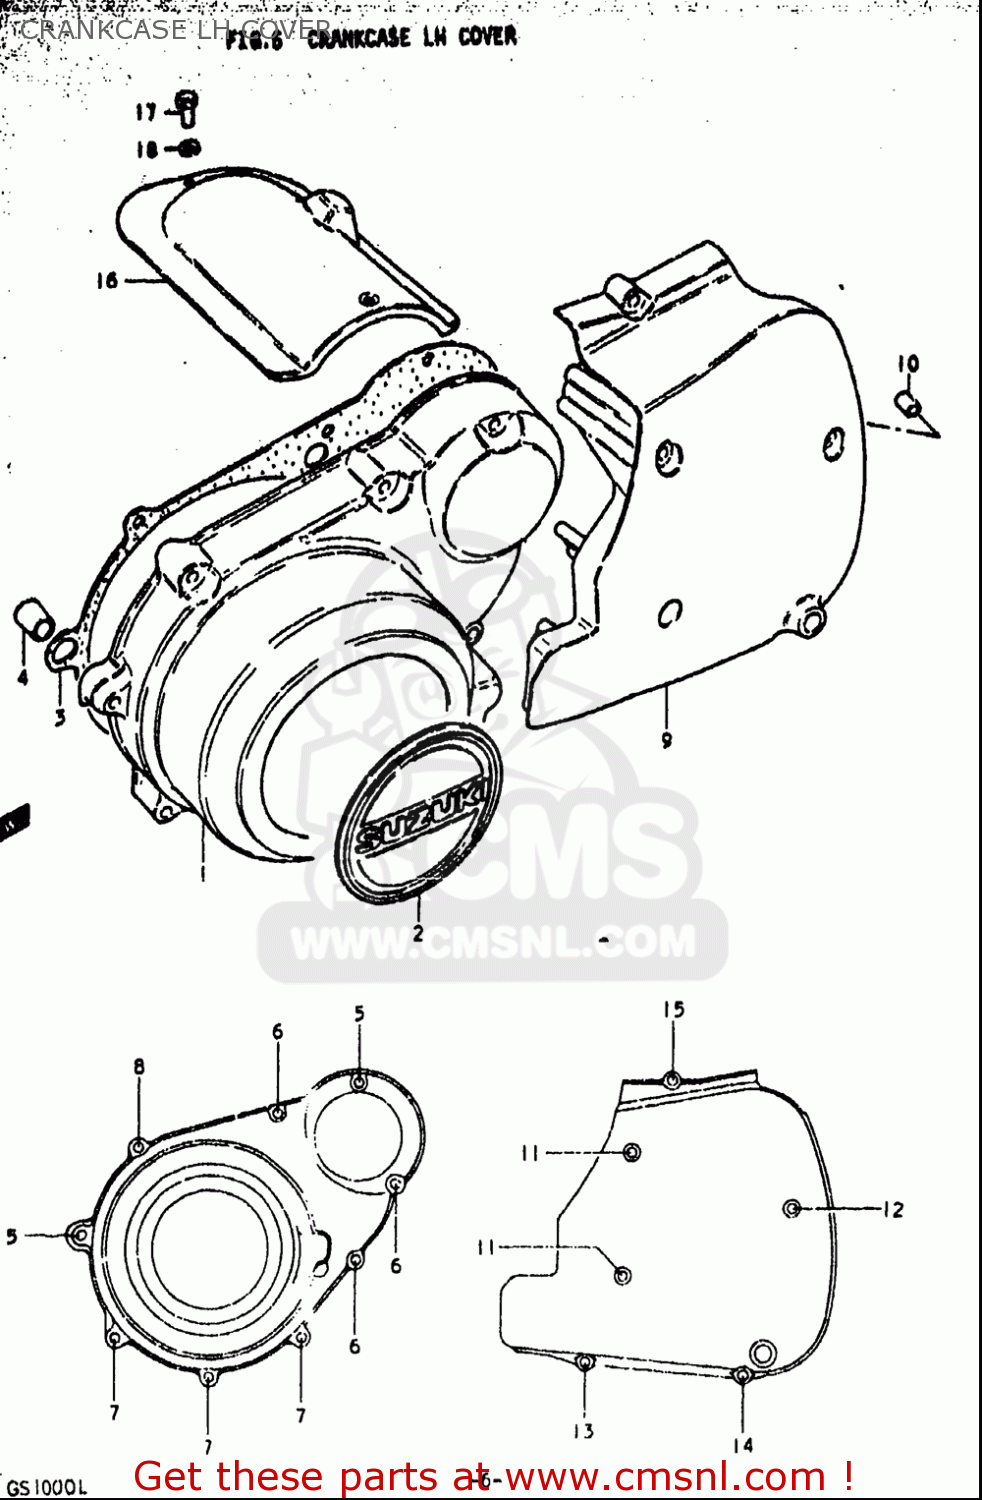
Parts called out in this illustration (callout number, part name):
1	COVER,MAGNETO
2	EMBLEM,MAGNETO COVER
3	GASKET,MAGNETO COVER (NAS)
4	PIN
5	SCREW
6	SCREW
7	SCREW
8	SCREW
10	PIN
11	SCREW(6X100)
12	SCREW
13	SCREW
14	SCREW
15	SCREW
16	COVER,STARTER MOTOR
17	BOLT
18	WASHER
